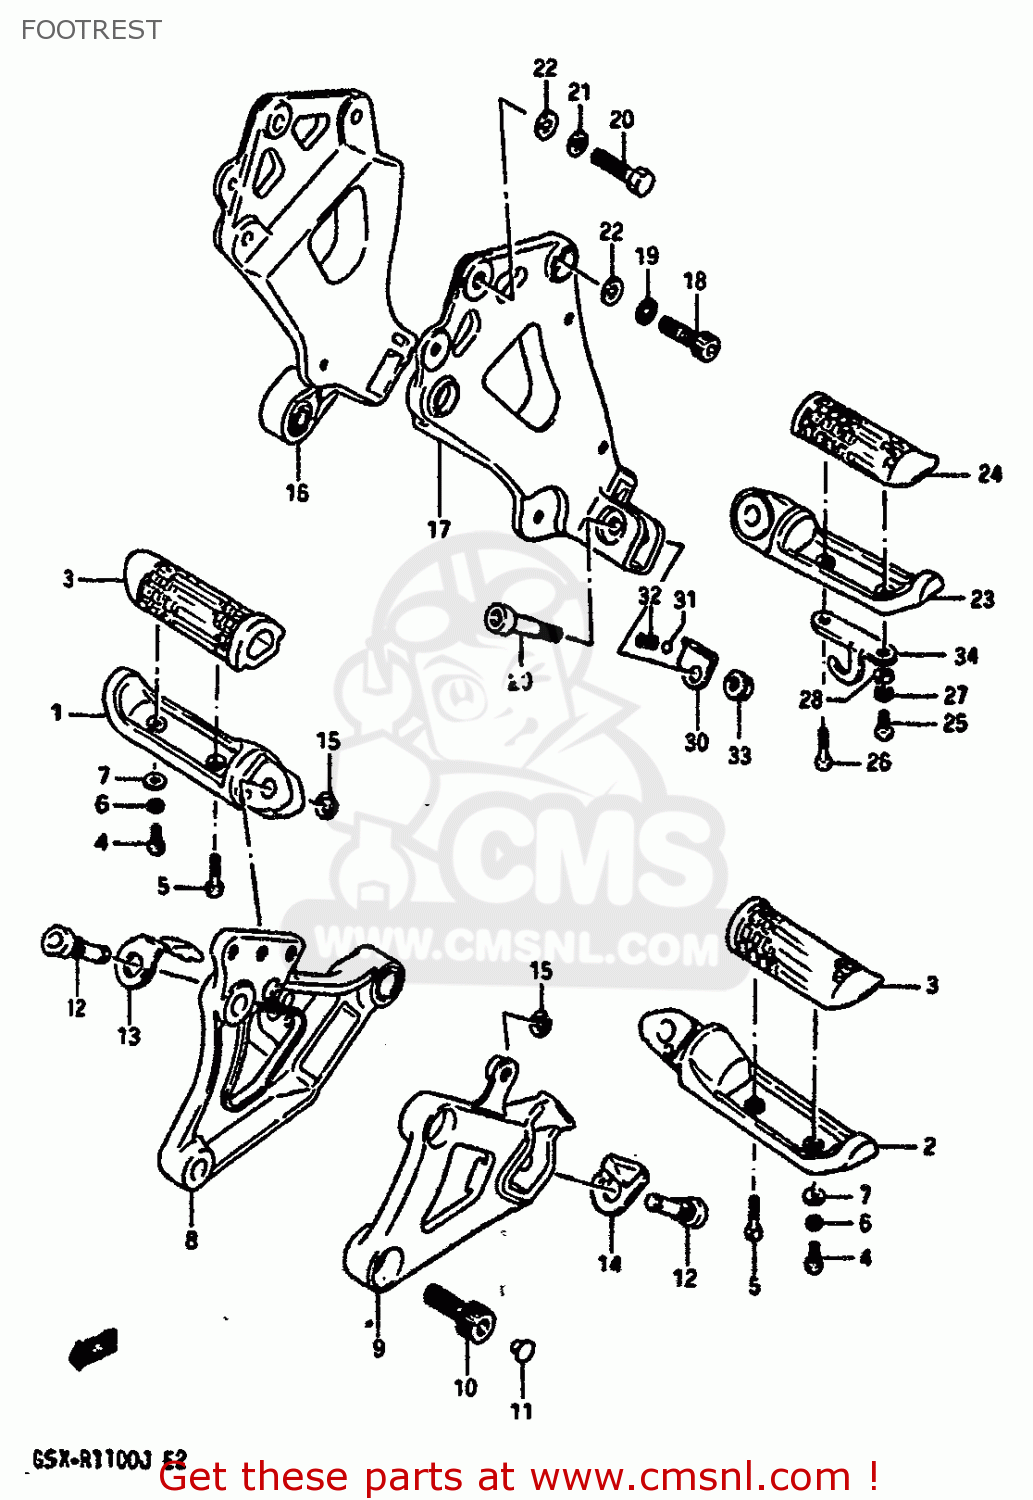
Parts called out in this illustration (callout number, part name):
1	FOOTREST ASSY,FR,R
2	FOOTREST ASSY,FR,L
3	RUBBER ASSY,FR FOOTREST
4	SCREW
5	SCREW 5X20
6	LOCK WASHER
7	WASHER
8	BRACKET,FOOTREST,R
9	BRACKET,FOOTREST,L
10	BOLT
11	CAP
12	BOLT,FR FOOTREST
13	CUSHION,FR FOOTREST,R
14	CUSHION,FR FOOTREST,L
15	E RING 6MM
16	BRACKET
17	BRACKET
18	BOLT
19	WASHER
20	BOLT 6X30
21	WASHER,LOCK
22	WASHER 6MM
23	FOOTREST ASSY,PILLION,L
24	RUBBER,PILLION FOOTREST
25	SCREW 5X20
26	SCREW(5X25)
27	WASHER,LOCK
28	WASHER,5MM
29	BOLT,PILLION FOOTREST
30	PLATE,SPRING STOP LH
31	BALL
32	SPRING
33	NUT
34	HOOK RH
